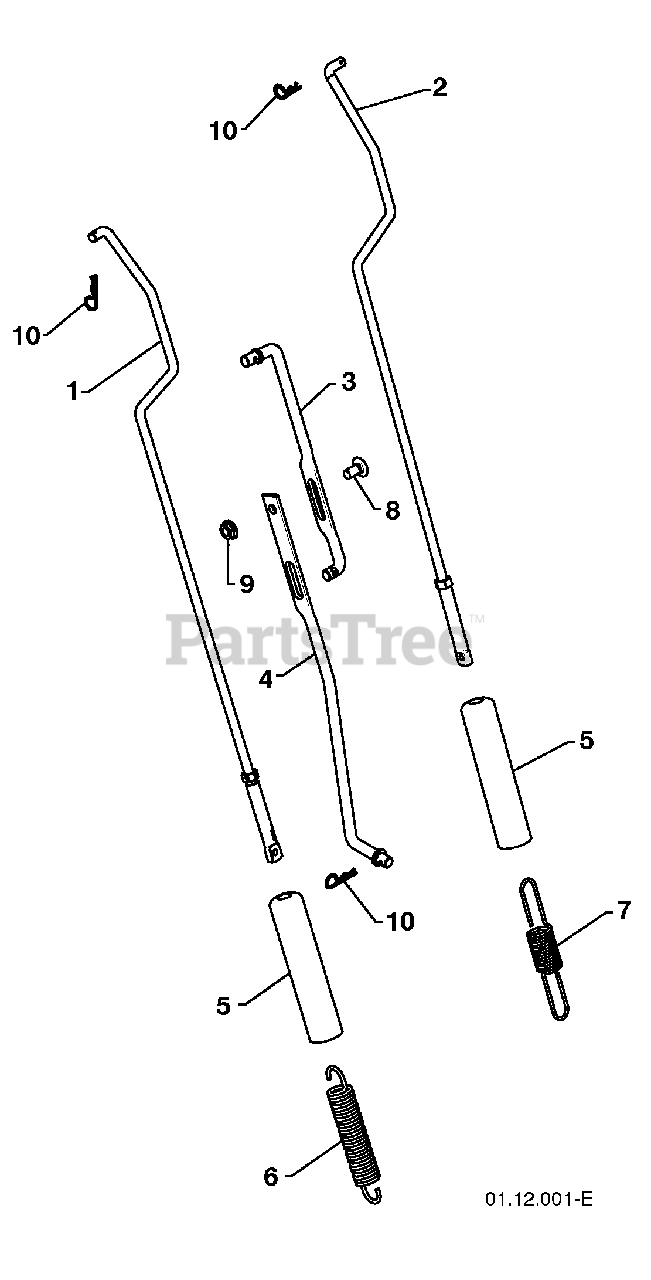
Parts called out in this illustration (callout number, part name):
1	IMPELLER ROD
2	TRACTION ROD
3	SHIFTER ROD TOP
4	SHIFTER ROD BOTTOM
5	SPRING SLEEVE
6	IMPELLER SPRING
7	TRACTION SPRING
8	CARRIAGE BOLT 5/16-18 X .75
9	NUT 5/16-18
10	RETAINER
